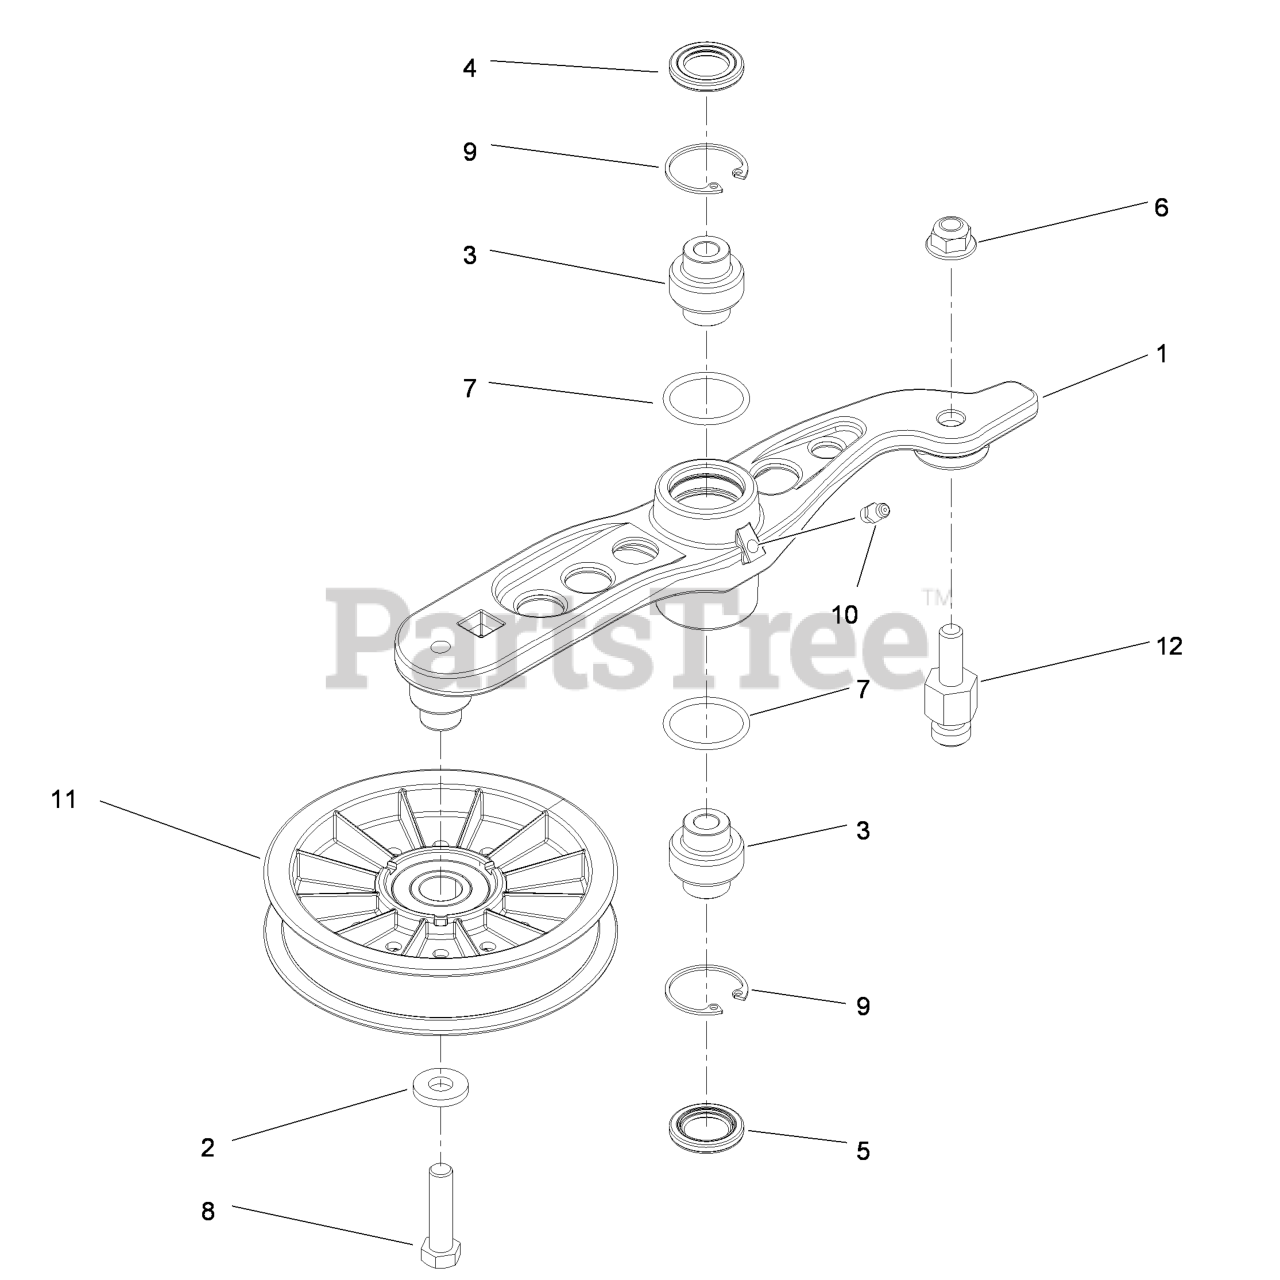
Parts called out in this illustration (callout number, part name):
1	Arm-Pump, Idler
3	BEARING-SPHERICAL
4	SEAL-LIP, DOUBLE
5	SEAL-LIP, SINGLE
6	Nut-Nyloc 3/8-16 Flg
8	SCREW-HH
9	RING-SNAP
10	FITTING-GREASE
11	PULLEY-IDLER
